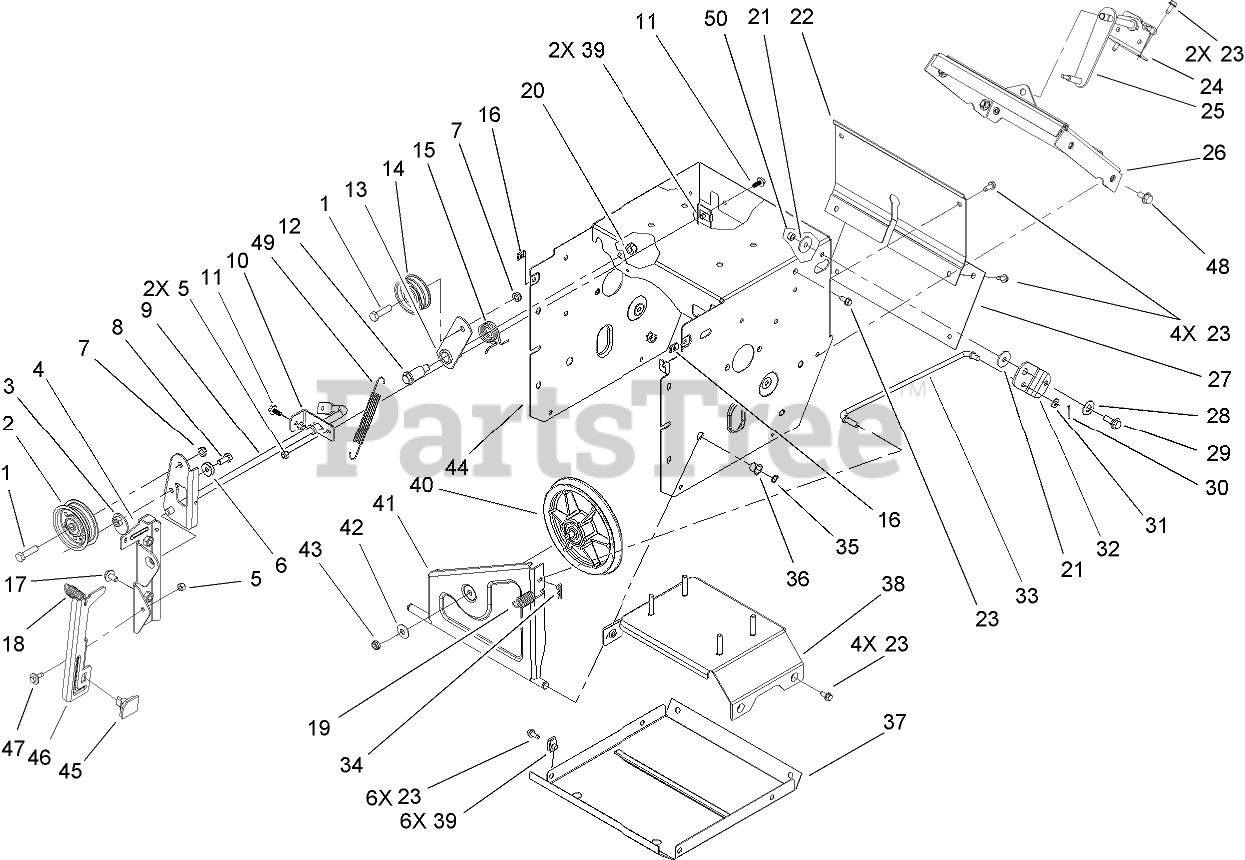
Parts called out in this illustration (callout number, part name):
1	SCREW-HH
2	PULLEY-IDLER
4	BRACKET-IDLER, IMPELLER
5	NUT-LOCK, NI
6	WASHER-BELLEVILLE
7	NUT-LOCK, NI
8	SCREW-HH
9	AUGER CLUTCH ASM
10	BRACKET-REAR, CLUTCH
11	SCREW-HHF
12	BOLT-SHOULDER
13	ARM-IDLER, TRACTION
14	PULLEY-IDLER
15	SPRING-TORSION, RH
16	NUT-SPEED, U-TYPE
17	SCREW-HHF
18	SPRING-EXTENSION
19	SPRING-EXTENSION
20	NUT-LOCK, NI
21	WASHER-PIVOT
22	COVER-UPPER
23	SCREW-HWH
24	BRACKET-SHIFT ROD
25	LEVER-CONTROL, TRACTION
26	SHIFT PLATE ASM
27	COVER-LOWER
28	WASHER
29	SCREW-SHOULDER
30	PIN-COTTER
31	WASHER-PLAIN
32	BELLCRANK-DRIVE
33	LINK-CONTROL, SPEED
34	PIN-COTTER
35	RING-RETAINING
36	BUSHING-NYLINER
37	PAN-BOTTOM
38	BRACE FRAME ASM
40	PULLEY-TRACTION
41	PULLEY PIVOT ASM
42	WASHER-BELLEVILLE
43	NUT-HEX
44	FRAME-TRACTION
45	PAD-BRAKE
46	ARM-BRAKE
47	SCREW-SHOULDER
48	SCREW-HWHTF
49	SPRING-EXTENSION
50	NUT-LOCK, NI
